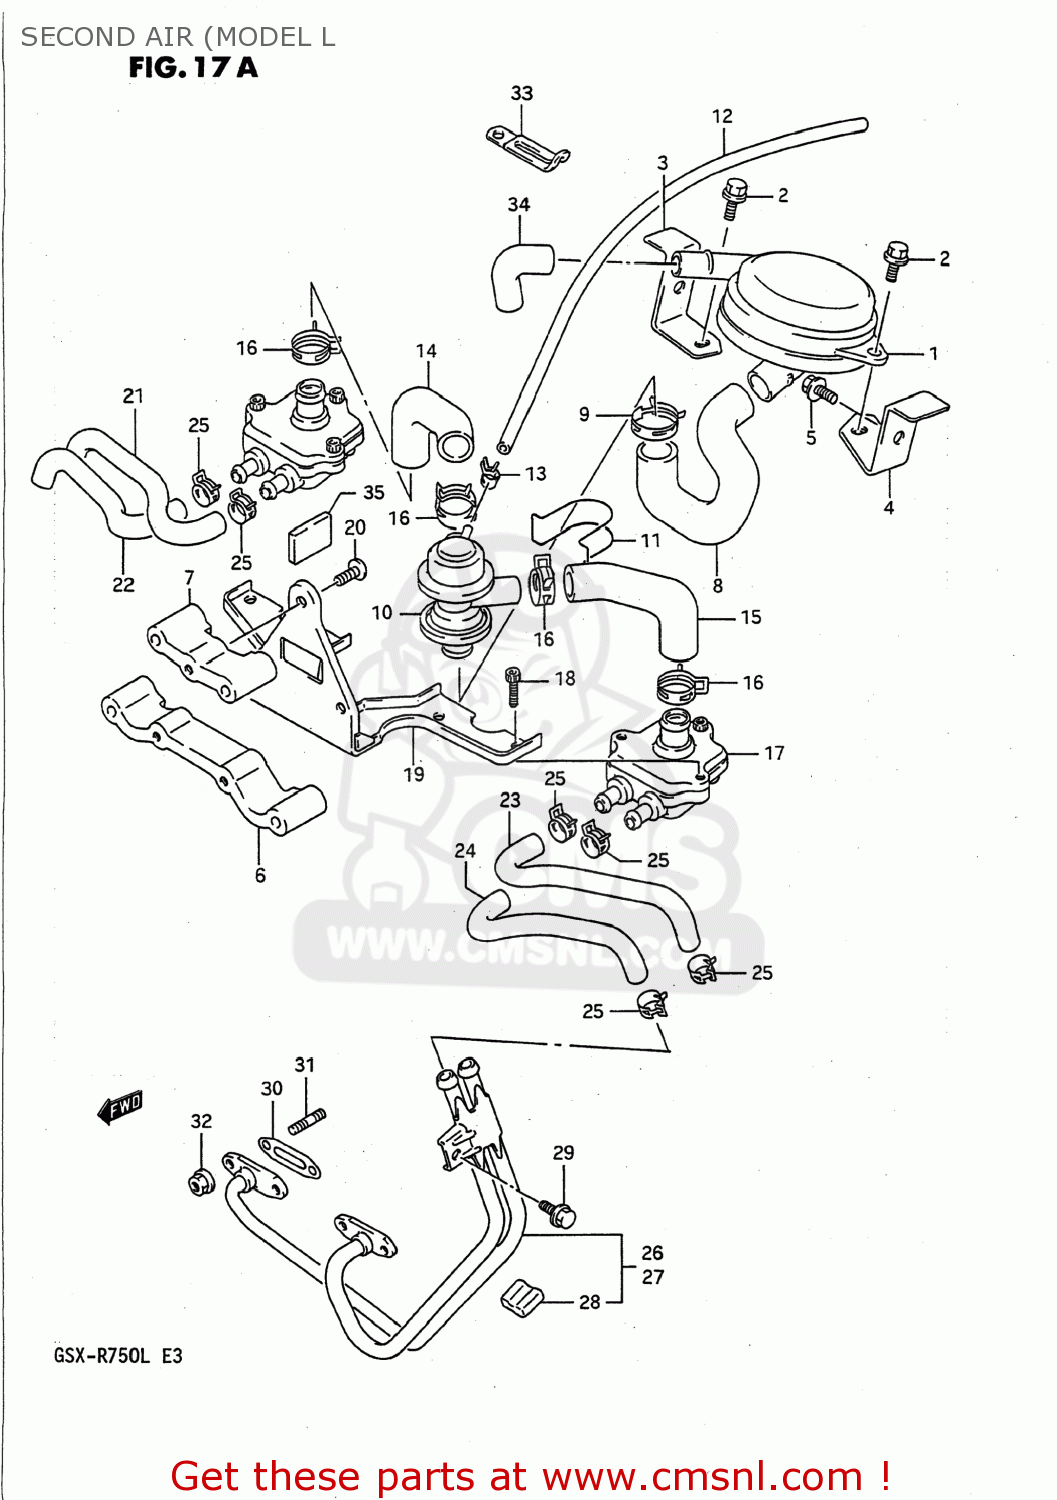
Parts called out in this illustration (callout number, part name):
1	CLEANER ASSEMBLY,SECOND AIR
2	BOLT
3	BRACKET,SECOND AIR CLEANER
4	BRACKET,SECOND AIR CLEANER
5	BOLT
6	SPACER,SECOND AIR BRACKET,LOWER
7	SPACER,SECOND AIR BRACKET,UPPER
8	HOSE,SECOND AIR NO.3
9	CLIP
10	VALVE ASSEMBLY,AIR SWITCH
11	CLAMP,SWITCHING VALVE
12	HOSE
13	CLAMP
14	HOSE,SECOND AIR NO.2,RIGHT
15	HOSE,SECOND AIR NO.2,LEFT
16	CLIP
17	VALVE ASSY,2ND AIR REED
18	BOLT
19	BRACKET,SECOND AIR VALVE
20	SCREW
21	HOSE,SECOND AIR NO.1,RIGHT,INLET
22	HOSE,SECOND AIR NO.1,RIGHT,OUTLET
23	HOSE,SECOND AIR NO.1,LEFT,INLET
24	HOSE,SECOND AIR NO.1,LEFT,OUTLET
25	CLIP
26	PIPE,SECOND AIR,RIGHT
27	PIPE,SECOND AIR,LEFT
28	(CA) CUSHION
29	BOLT 6X12
30	GASKET,SECOND AIR PIPE (NAS)
31	STUD BOLT
32	NUT 6MM
33	CLAMP L:35
34	(CA) HOSE,SECOND AIR CLEANER
35	CUSHION
